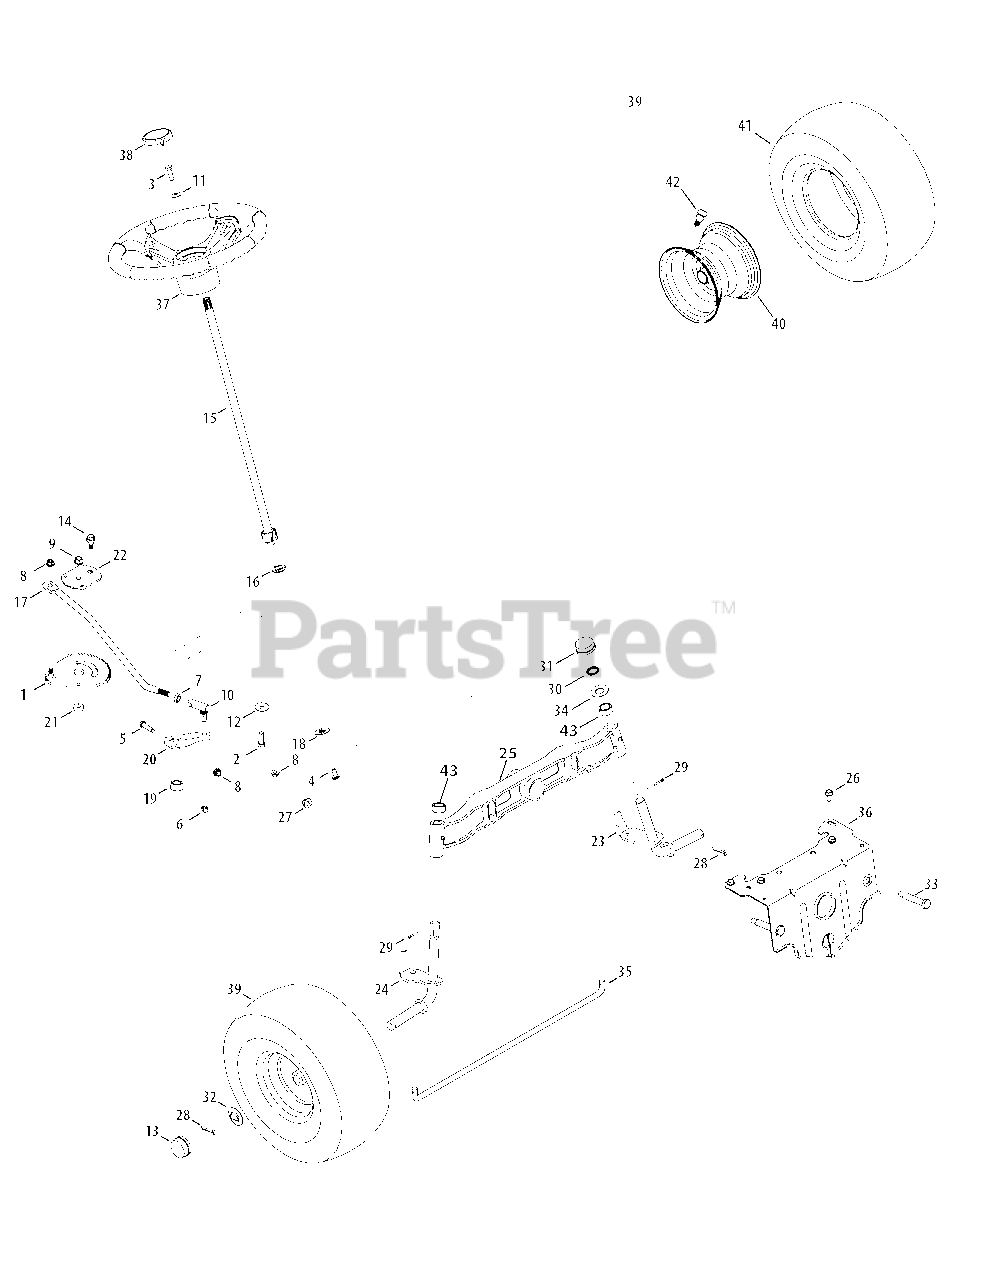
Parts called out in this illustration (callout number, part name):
1	Gear Assembly, Steering
2	Hex Head Screw, 3/8-16 x 1.00
3	Screw, 5/16-18, 1.00, Gr5, Lock
4	Screw, Mach, 5/16-18, 0.750
5	Screw, 5/16-18, 1.75, Gr5
6	Nut, Jam Lock, 3/8-24
7	Nut, Jam, 7/16-20, Gr2
8	Nut, Flange Lock, 5/16-18, Grf
9	Nut, Flange Lock, 3/8-16, Grf
10	Ball Joint, 7/16-20, Lock
11	Washer, Bell, .340 x .872 x .060
12	Bevel Washer, .390 x 1.130 x .062
13	Hub Cap
14	Shoulder Screw, 5/16-18
15	Steering Shaft, 5/8 Spline
16	Bearing, Flange, Hex 5/8
17	Drag Link, Steering
18	Cap, 1.25 x .16
19	Spacer, .710 ID x .125 OD x .56
20	Steering, Block
21	Spacer, .38 x .854 x .20
22	Stabilizer Gear Plate
23	Axle Assembly LH
24	Axle Assembly RH
25	Pivot Axle, Cast
26	Screw, 5/16-18, 0.750
27	Nut, Flange Lock, 3/8-16, GrF
28	Pin, Cotter, 5/32, 1.25
29	Pin, Cotter, 1/8 x 0.75
30	Push Nut, 3/4
31	Hub Cap
32	Washer, Flat, .781 x 1.59
33	Screw, Shlder, .500 x 2.380, 3/8-16
34	Flat Washer, .78 x 1.59 x .060
35	Tie Rod
36	Pivot Bar Bracket
37	Steering Wheel, Softgrip
38	Cap, Steering Wheel (Crafts. logo)
39	Wheel Assembly
41	Tire, 15 x 6 x 6 Rd. Shoulder
42	Valve Stem
43	Spacer, .71 x .125 x .56
